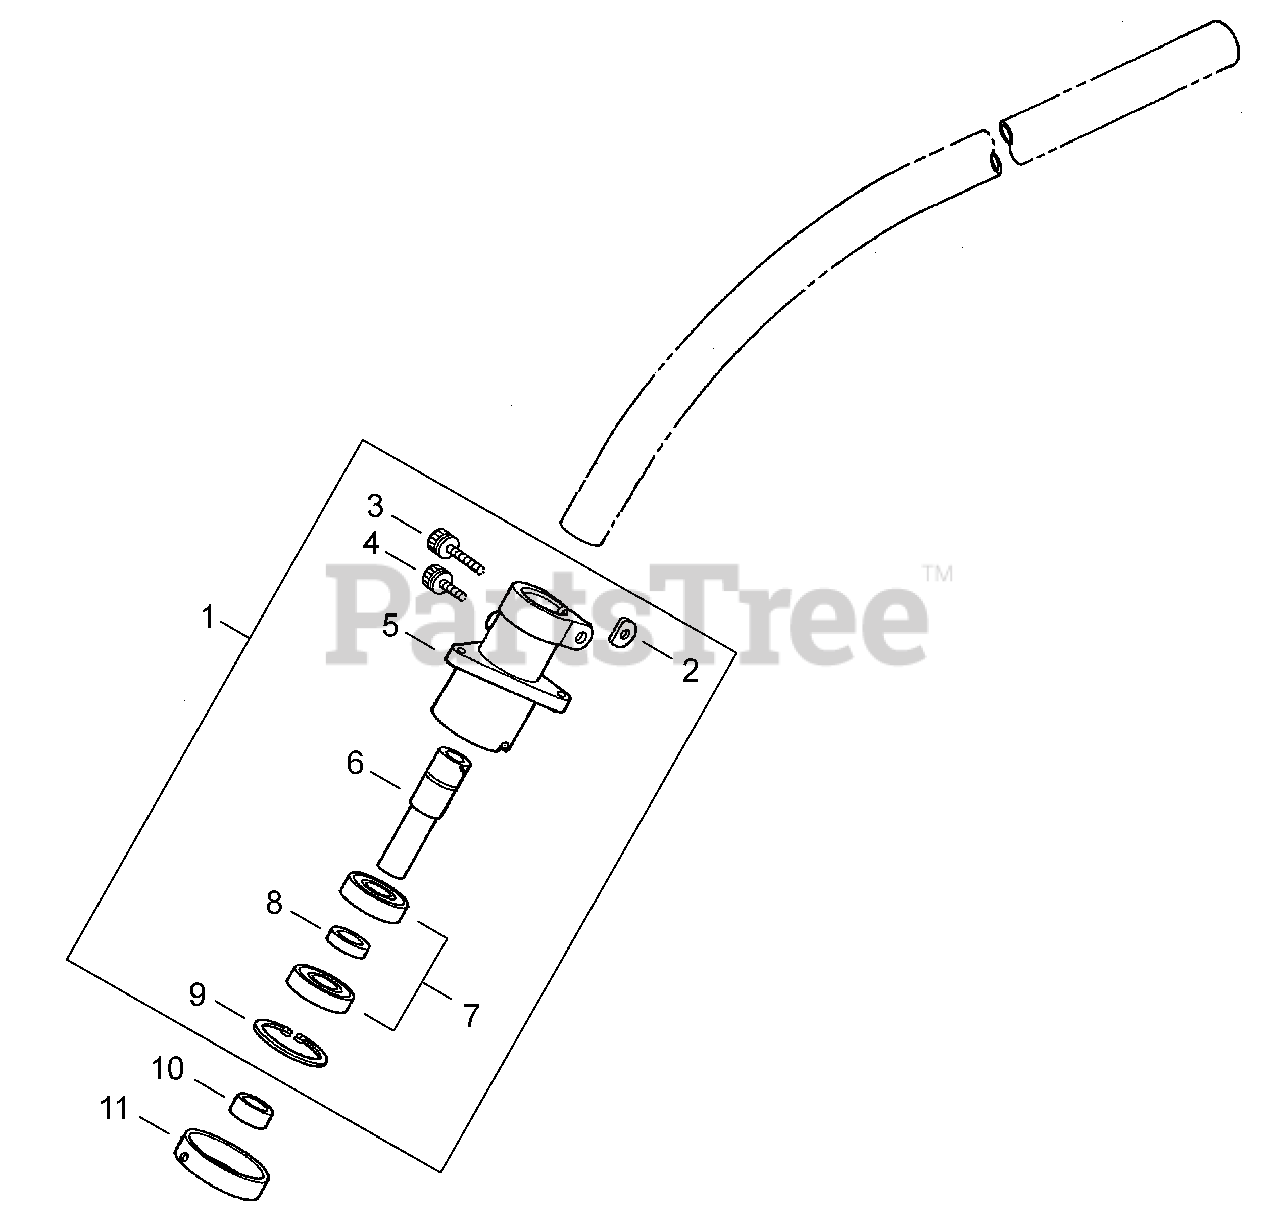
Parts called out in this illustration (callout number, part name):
1	MAIN PIPE ASSY
2	PIPE, MAIN
3	LABEL - CAUTION
5	DRIVESHAFT - FLEXIBLE
6	LABEL - INSTRUCTION
